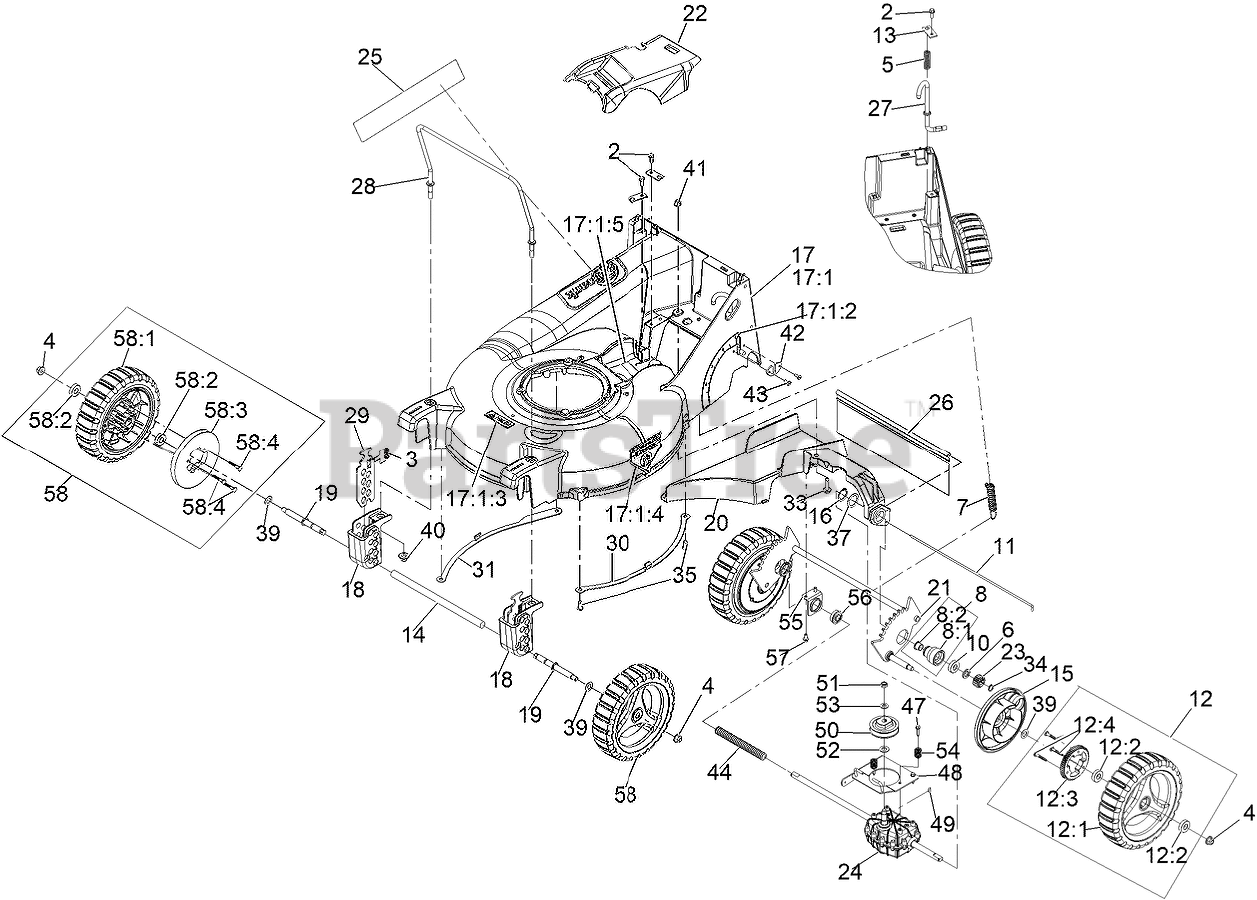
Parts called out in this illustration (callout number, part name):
2	SCREW-HWH
3	SPRING-COMPRESSION
4	NUT-HF, NI
5	SPRING-COMPRESSION
6	SPACER-BUSHING
7	SPRING-EXTENSION
8	HOUSING ASM
8:1	HOUSING-BEARING
8:2	BEARING-FLANGE
10	BEARING-BALL
11	ROD,SHIELD
12	WHEEL ASM, 9 W/GEAR
12:1	WHEEL ASM, 9
12:2	BEARING-BALL
12:3	GEAR-WHEEL, 52T
12:4	STUD-DRIVE
13	BRACKET,MOUNT
14	ROD,BUMPER
15	COVER,GEAR
16	RING-RETAINING
17	ASM-DECK EC21
17:1:2	DECAL-HEIGHT OF CUT
17:1:3	DECAL-WARNING, BLADE
17:1:4	DECAL-DANGER
17:1:5	DECAL-DANGER
18	BLOCK,FRONT QUADRANT
19	AXLE-WHEEL
20	BRACKET-TRANSMISSION AND
21	WLD,REAR AXLE P21
22	COVER-BELT
23	GEAR-PINION, 15T
24	TRANSMISSION-HD, 4.5/1
25	Decal-Commercial 21 V-Series
26	SHIELD-TRAILING P21
27	ROD-HEIGHT ADJ P21
28	Guard-Front Motor
29	PLATE, FRONT HEIGHT
33	SCREW-HWHTF
34	RING-RETAINING
35	SCREW-BHTF
39	WASHER-PLAIN
40	Nut-Nyloc 3/8-16 Flg
41	NUT-HF, NI
42	PLATE,WEAR
43	RIVET-BLIND
44	COVER-SHAFT-DRIVE
47	SCREW-SPECIAL
48	TRANSMISSION PLATE ASM
49	KEY-WOODRUFF
51	NUT-HEX
52	WASHER-THRUST
53	WASHER-FLAT
54	SPRING,COMPRESSION
55	MOUNT-BEARING
56	BEARING-BALL
57	SCREW-HWH
58	ASM-Wheel W/ Weight
58:1	WHEEL ASM, 9
58:2	BEARING-BALL
58:3	WEIGHT-WHEEL
58:4	STUD-DRIVE
